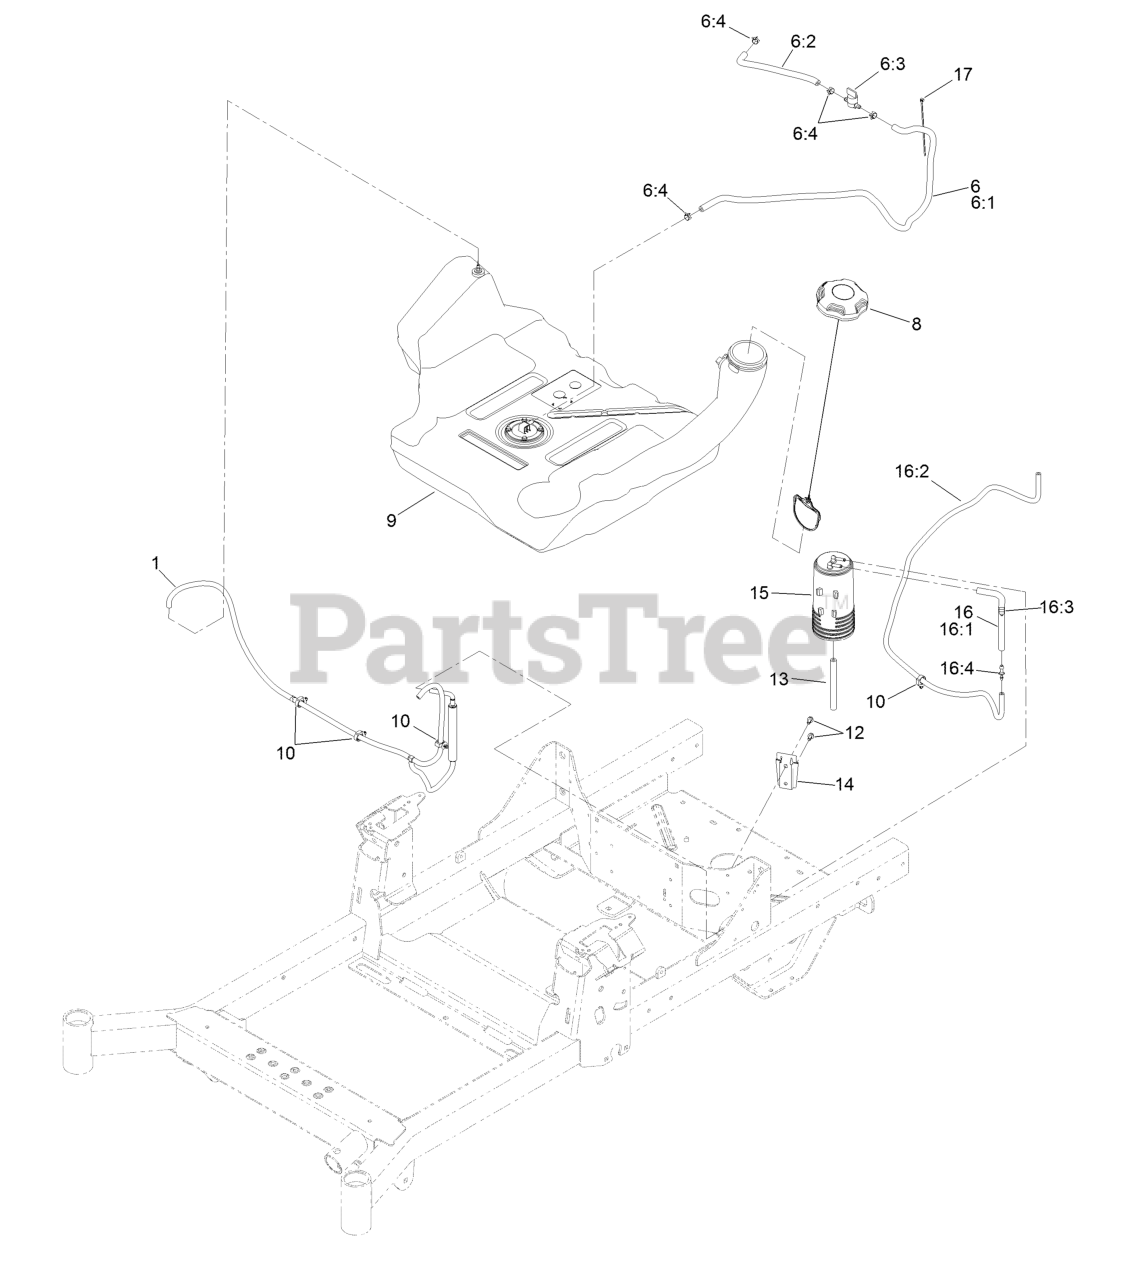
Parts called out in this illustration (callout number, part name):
1	Vent Hose ASM
6	Fuel Hose ASM
6:1	Hose-Fuel
6:2	Hose-Fuel
6:3	Valve-Fuel
6:4	Clamp-Hose
8	Cap-Fuel
9	Tank-Fuel
12	Screw-HWH
13	Hose-Fuel
14	Bracket-Canister, Carbon
15	Canister-Carbon, 800Cc
16	Vent Hose ASM
16:1	Hose-Fuel
16:2	Hose-Fuel
16:3	Cartridge-Valve, Check
16:4	Fitting-Straight
17	Tie-Cable
